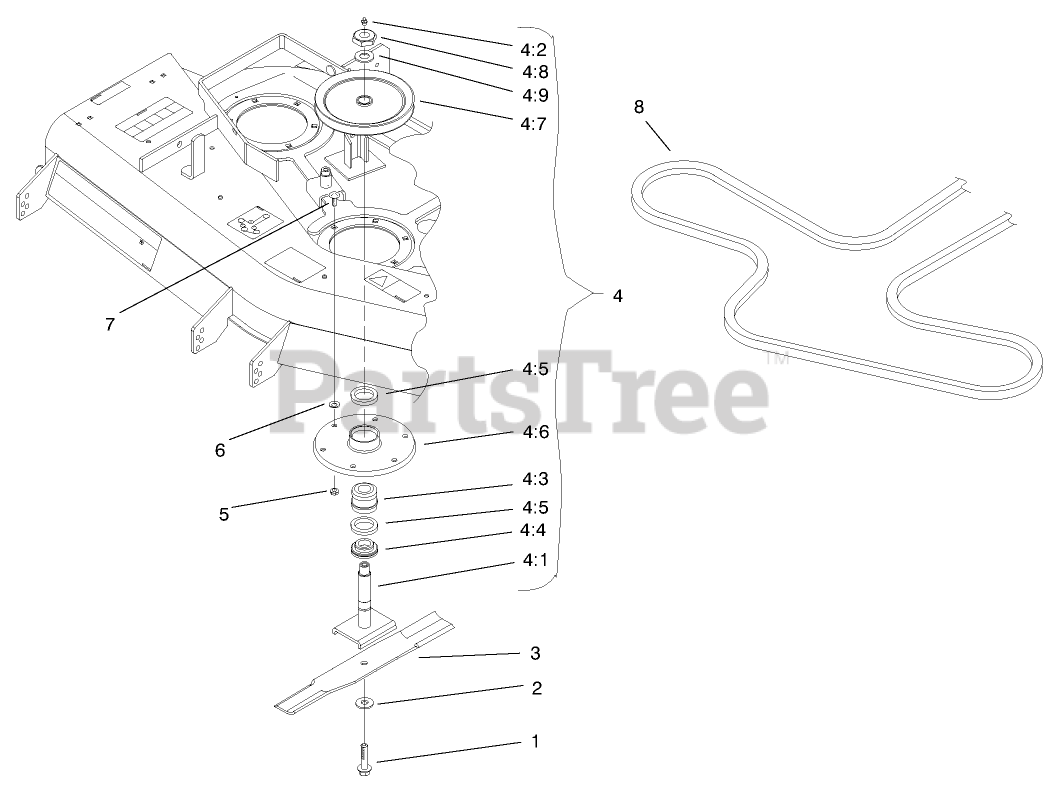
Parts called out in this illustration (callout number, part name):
1	BOLT-BLADE
2	Washer-Flat
3	BLADE-SAIL, EXTRA HIGH
4	SPINDLE HOUSING ASM
4:1	SPINDLE SHAFT ASM
4:2	FITTING-GREASE
4:3	BEARING ASM
4:4	SPACER
4:5	SEAL-OIL
4:6	HOUSING-SPINDLE
4:7	PULLEY AND HUB ASM
4:8	NUT-HEX
4:9	WASHER
5	NUT-HF
6	WASHER-FLAT
7	SCREW-CARR
8	BELT-DECK (52)
